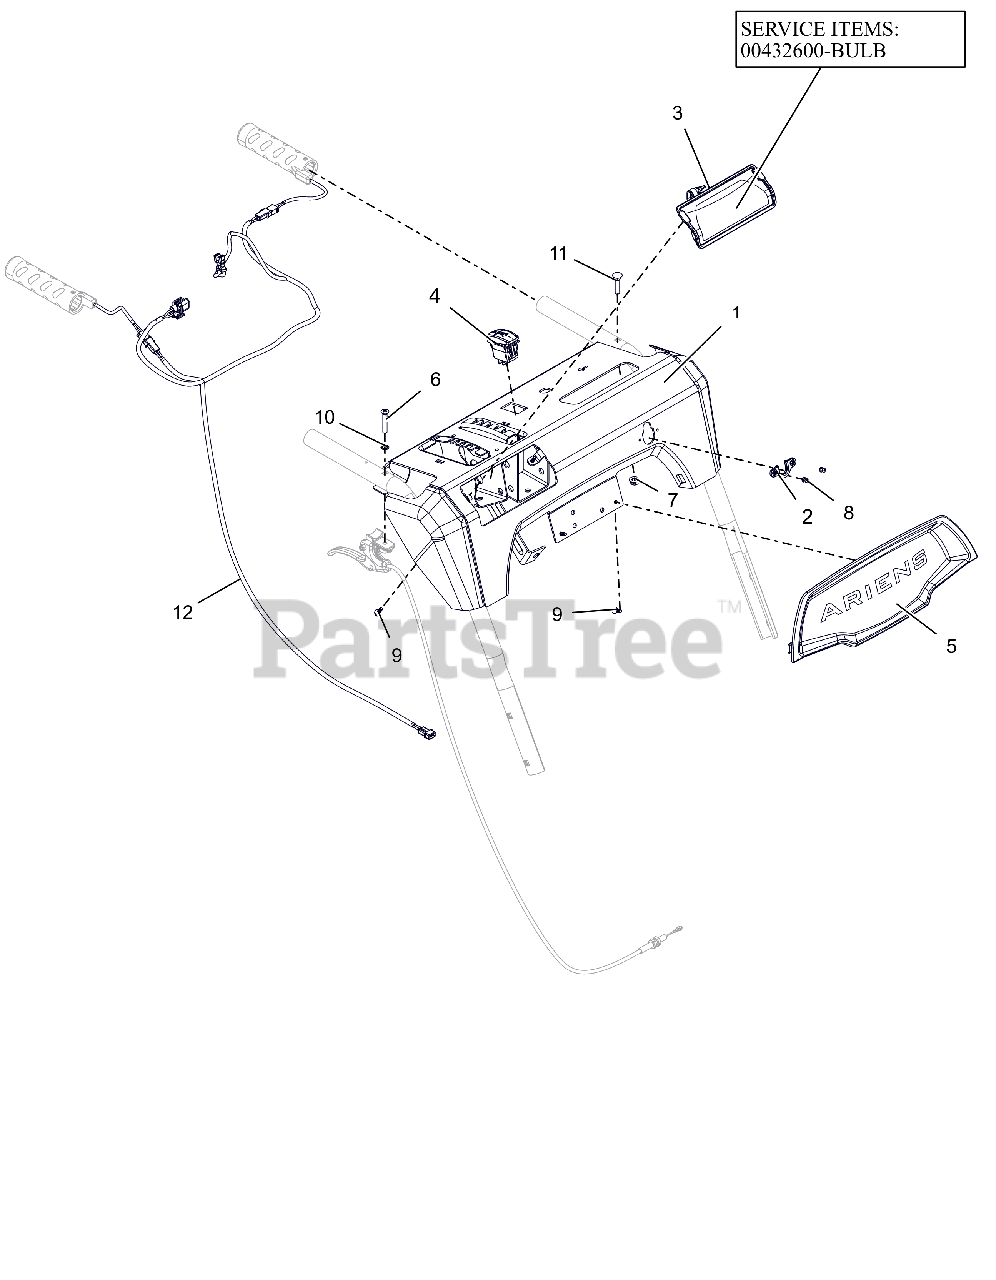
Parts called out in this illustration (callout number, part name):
1	CONTROL PANEL W/DECAL FRIC-TRK
2	GROMMET, CABLE, QUICK TURN 2
3	HEADLIGHT ASY, HALO 20W 2SHOT
3	BULB, LIGHT-HALOGEN 20W
4	SWITCH,ROCKER SPST-ON/OFF
5	BEZEL, DASH - ARIENS LG DASH
6	SCR-MCH .25-20X1.50 OVAL HD
7	@NUT-LK-CTR-FLG .25-20 YWZC
8	RVT-POP #43 .125X.313 STL ZINC
9	SCR-TAP #10X.50 BOSS INDHXHD
10	WSHR-LK-INT .250 TH TYA
11	BLT-RDHDXLSQNK.25-20X1.25 G5ZC
12	HARNESS, LIGHT & WARMER
